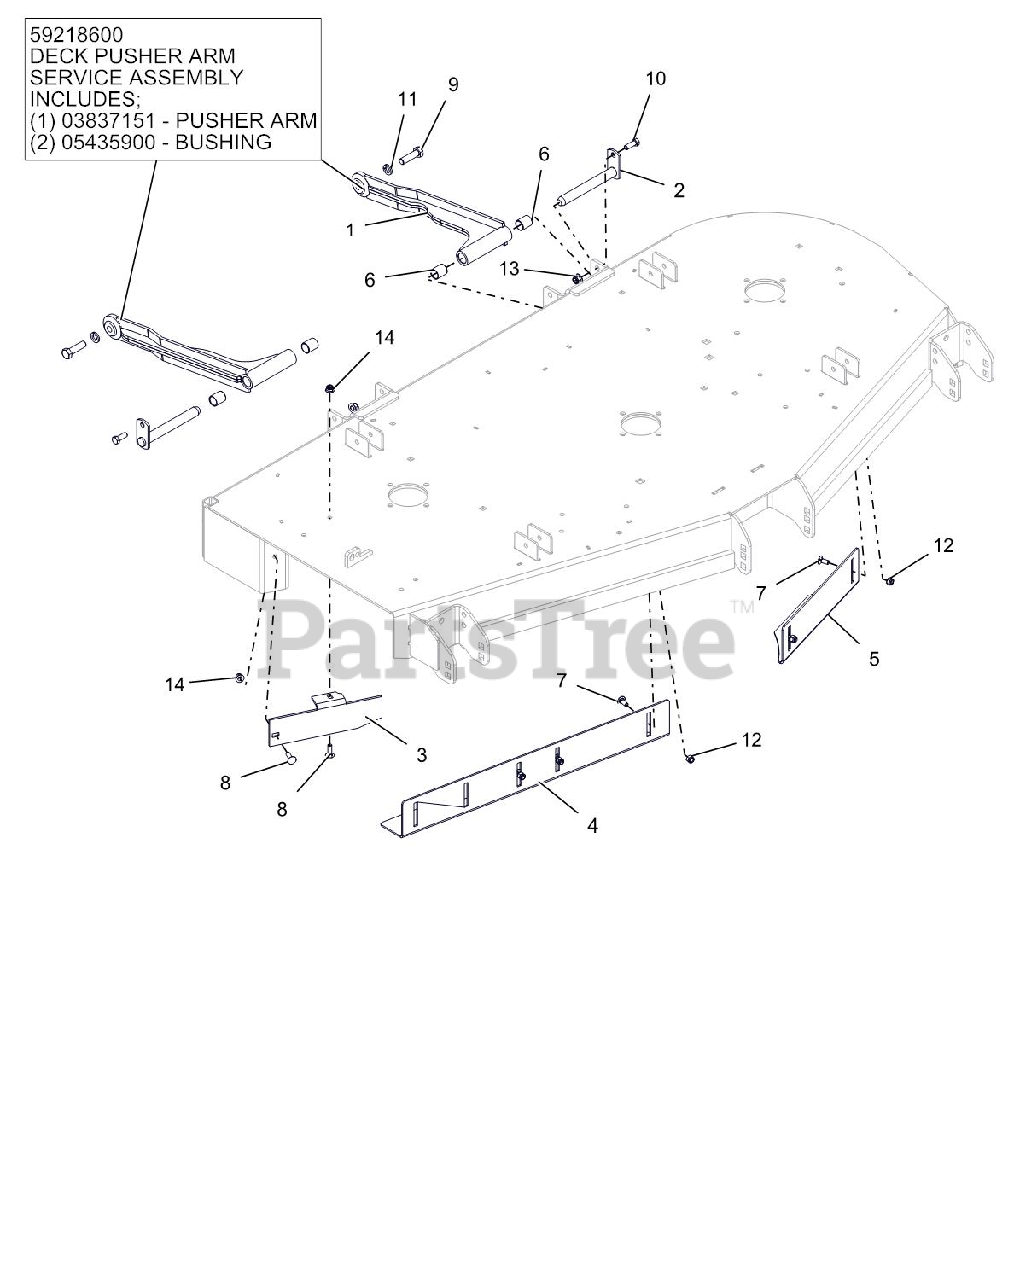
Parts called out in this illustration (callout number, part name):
1	BRG, .750 X .875 X 1.000
1	DECK STABILIZER ARM W/BUSHINGS
1	DECK STABILIZER ARM - BLACK
2	WELDMENT, MOWER MTG. PIN
3	60" DISCHARGE BAFFLE - RED
4	60" RH VACUUM BAFFLE - BLK
5	60" LH VACUUM BAFFLE - BLK
6	BRG, .750 X .875 X 1.000
7	@BLT-RDHDSQNK .31-18X.75 G5YZ
8	@BLT-RDHDSQNK .31-18X1.00 G5YZ
9	BLT-HEX .50-13X1.75 GR5EP80 YZ
10	@BLT-HEX .38-16X1.00 GR5 YWZC
11	@WSHR-LK .50X.125 REG YWZC
12	@NUT-LK-NYL .312-18 YWZC
13	@NUT-LK-NYL-FLG .38-16 YWZC
14	@NUT-LK-NYL-FLG .31-18 YWZC
